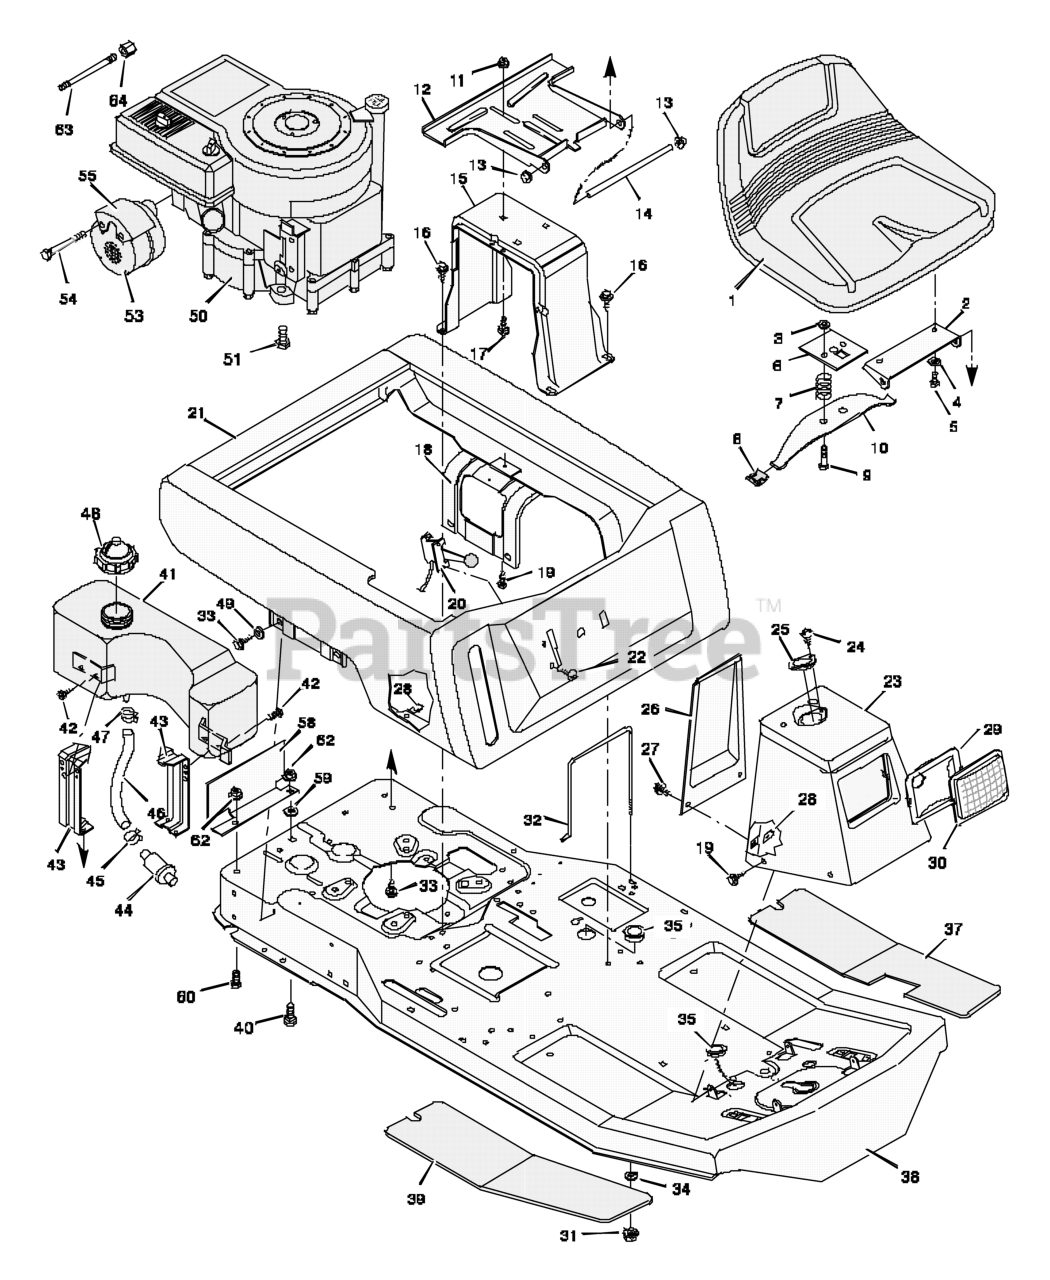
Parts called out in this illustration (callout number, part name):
2	Hinge, Seat
3	Retainer
4	Lockwasher
5	Bolt, Hex
6	Plate, Seat Switch
7	Spring, Compression
8	Glide, Seat Spring
9	Bolt, Shoulder
10	Spring, Seat
11	Locknut, Flange
12	Bracket, Seat Pivot
13	Cap, Push On
14	Rod, Seat Hinge
15	Support, Seat
17	Bolt, Carriage
18	Support, Body
20	Throttle Control
23	Console Assembly
25	Bearing, Steering Post
26	Console, Plate
29	Reflector
31	Locknut
32	Clamp, Battery
34	Washer
35	Grommet
37	Mat, Left
38	Frame Assembly
39	Mat, Right
40	Bolt, Carriage
41	Tank, Fuel
43	Bracket, Fuel Tank
44	Filter, Fuel
46	Line, Fuel
47	Clamp
48	Cap, Fuel
49	Washer
50	Engine *
51	Bolt, Engine Mount
53	Muffler
55	Shield, Heat
58	Shield, Heat
59	Washer
60	Bolt
62	Locknut, Flange
63	Pipe, Oil Drain
64	Cap, Oil Drain
